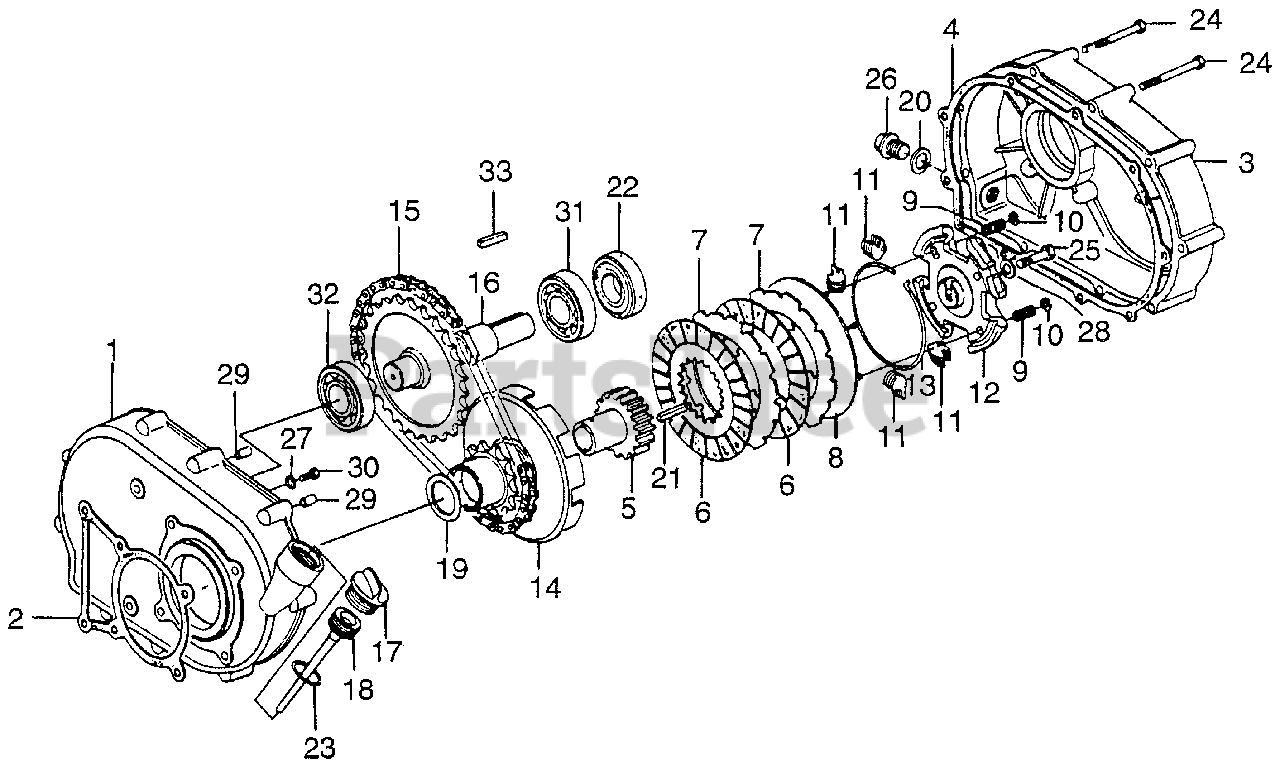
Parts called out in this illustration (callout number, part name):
1	CASE, REDUCTION
2	GASKET, REDUCTION CASE (NOT AVAILABLE)
3	COVER, REDUCTION
4	GASKET, REDUCTION
5	CENTER, CLUTCH (NOT AVAILABLE)
6	DISK, CLUTCH FRICTION
7	PLATE, CLUTCH
8	PLATE, CLUTCH PRESSURE
9	SPRING, CLUTCH FREE
10	HOLDER, CLUTCH SPRING
11	WEIGHT, CLUTCH
12	HOLDER, CLUTCH WEIGHT
13	CENTER, CLUTCH WEIGHT
14	SPROCKET, DRIVE (NOT AVAILABLE)
15	CHAIN, DRIVE (RK428SH-36LE)
16	SHAFT, P.T.O. (28T)
17	CAP, REDUCTION OIL
18	DIPSTICK, OIL (NOT AVAILABLE)
19	WASHER (22MM) (NOT AVAILABLE)
20	WASHER, DRAIN PLUG (12MM)
21	KEY, CLUTCH CENTER (NOT AVAILABLE)
22	OIL SEAL (PJ30507)
23	O-RING (26X2.7)
24	BOLT, HEX. (6X56) (NOT AVAILABLE)
25	BOLT, HEX. (8X36)
25	BOLT, HEX. (8X35)
26	BOLT, DRAIN PLUG (12MM)
27	WASHER, PLAIN (8MM)
28	WASHER, SPRING (8MM)
29	PIN A, DOWEL (8X10)
30	BOLT, HEX. (8X25) (NOT AVAILABLE)
31	BEARING, RADIAL BALL (6205)
32	BEARING, RADIAL BALL (6206)
33	KEY (7X7X33)
